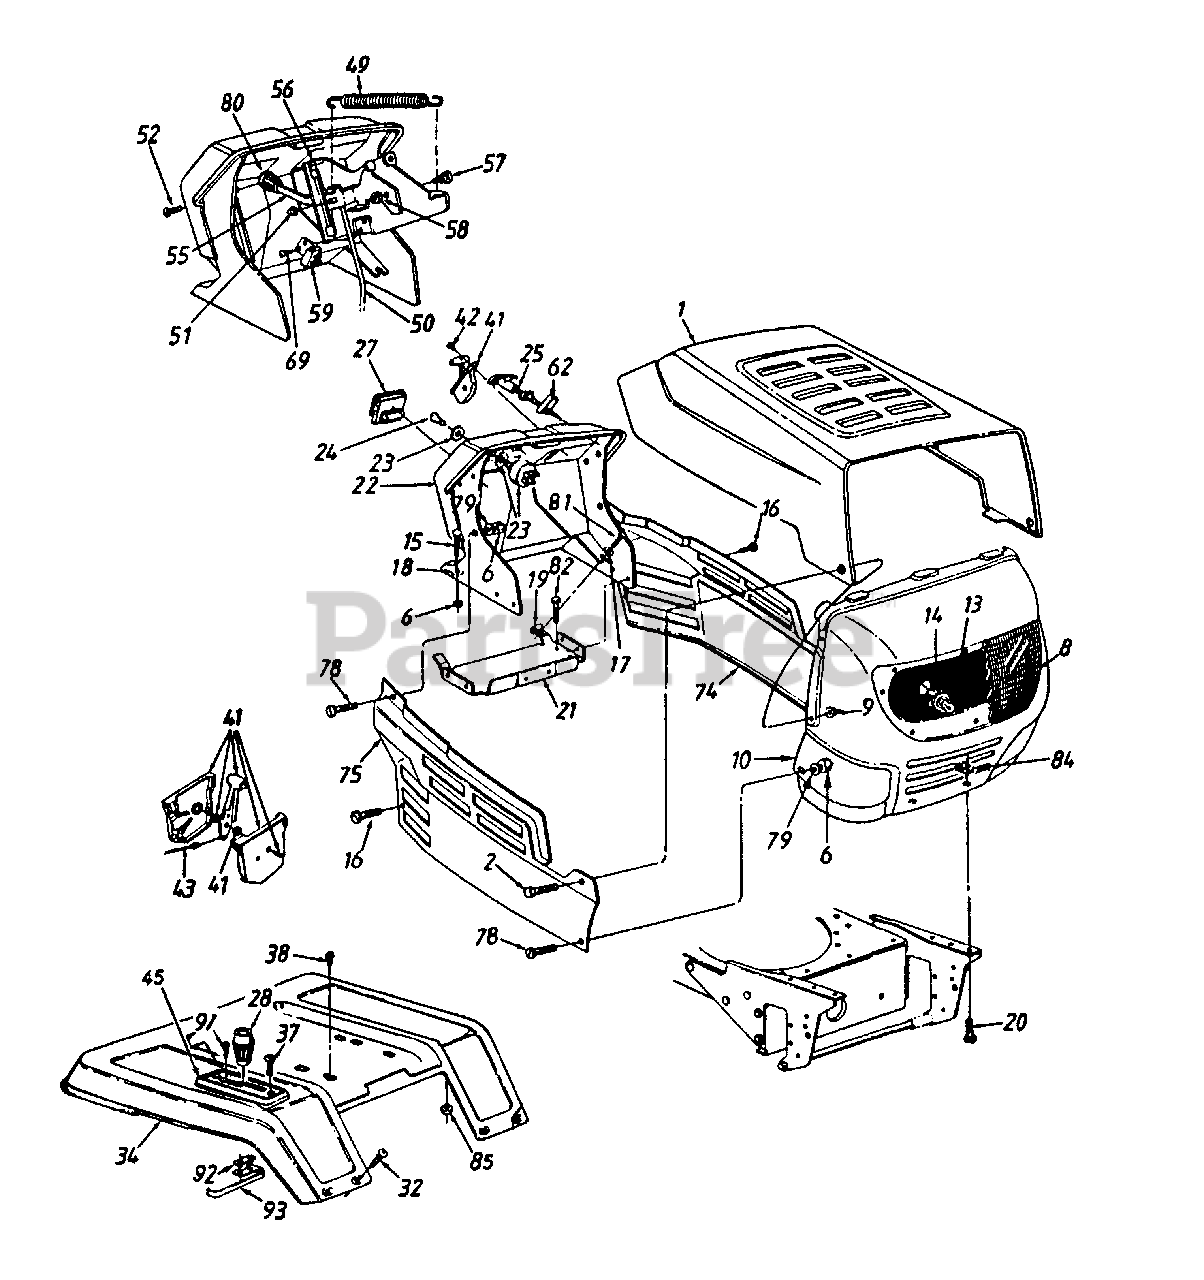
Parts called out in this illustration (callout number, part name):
6	Hex Nut 1/4-20 Thd.
8	Headlight Lens
9	Flange L-Nut 1/4-20 Thd.
13	Lamp
14	Socket
15	Carriage Bolt 1/4-20 x 1.0" Lg.
16	Hex Wash. Hd. TT-Tap Scr. 1/4-20 x .5" Lg.
17	Fl-Wash. .281" I.D. x .73" O.D.
18	Bolt Retainer 1/4" I.D.
19	Speed Nut 1/4-20 Thd.
20	Hex Bolt 5/16-18 x .75" Lg.
23	Ignition Switch
24	Ignition Key
25	Choke Control
27	Ammeter
28	Shift Knob
32	Carriage Bolt 1/4-20 x .5" Lg.
38	Hex Wash. Hd. AB-Tap Scr. 5/16 x .75" Lg.
41	Throttle Box Ass'y.
42	Truss Mach. AB-Tap Scr. #10 x .5" Lg.
43	Throttle Control Wire 35" Lg.
45	Selector Plate
49	Ext. Spring 5.06" Lg.
50	Deck Control Rod
51	Speed Nut 1/4" Rod
52	Torx Mach. Scr. 1/4 x .62" Lg.
55	PTO Lever
58	Hex L-Nut 5/16-18 Thd.
59	Safety Switch
62	Retainer Clip
69	Hex Wash. Hd. B-Tap Scr.#10 x .38" Lg.
79	Bell-Wash. 1/4" I.D.
80	Knob
81	Hex TT-Tap Scr. 1/4-20 x .75" Lg.
82	Hex AB-Tap Scr. 1/4 x .62" Lg.
84	U-Nut 5/16-18 Thd.
85	Hex Sems Nut 1/4-20 Thd.
91	Hex Wash. Hd. AB-Tap Scr.#8 x .5" Lg.
92	Insulator Nut Plate
93	Reverse Safety Switch
